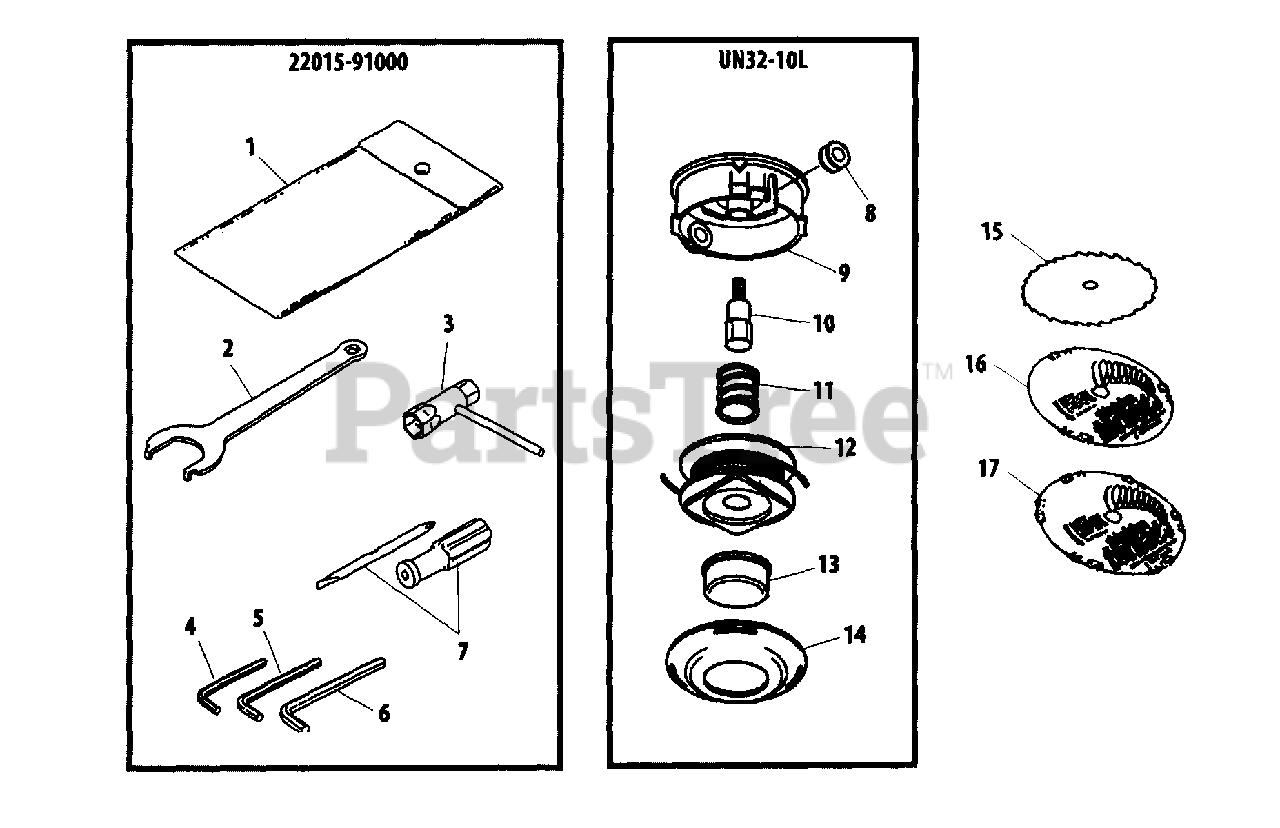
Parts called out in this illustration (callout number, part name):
1	BAG, TOOL
2	SPANNER
3	WRENCH, SPARK PLUG -- 17×9 MM
4	WRENCH, ALLEN 4 MM
5	WRENCH, ALLEN 5 MM
6	WRENCH, ALLEN 3 MM
7	SCREWDRIVER
10	SHAFT BOLT 10 MM LH
15	BLADE - 30 TOOTH -- 9"
16	BLADE - 6 TOOTH -- 9" TORNADO
17	BLADE - 12 TOOTH -- 9" TORNADO
22015-91000	TOOL SET
UN32-10L	TRIMMER HEAD ASSY
